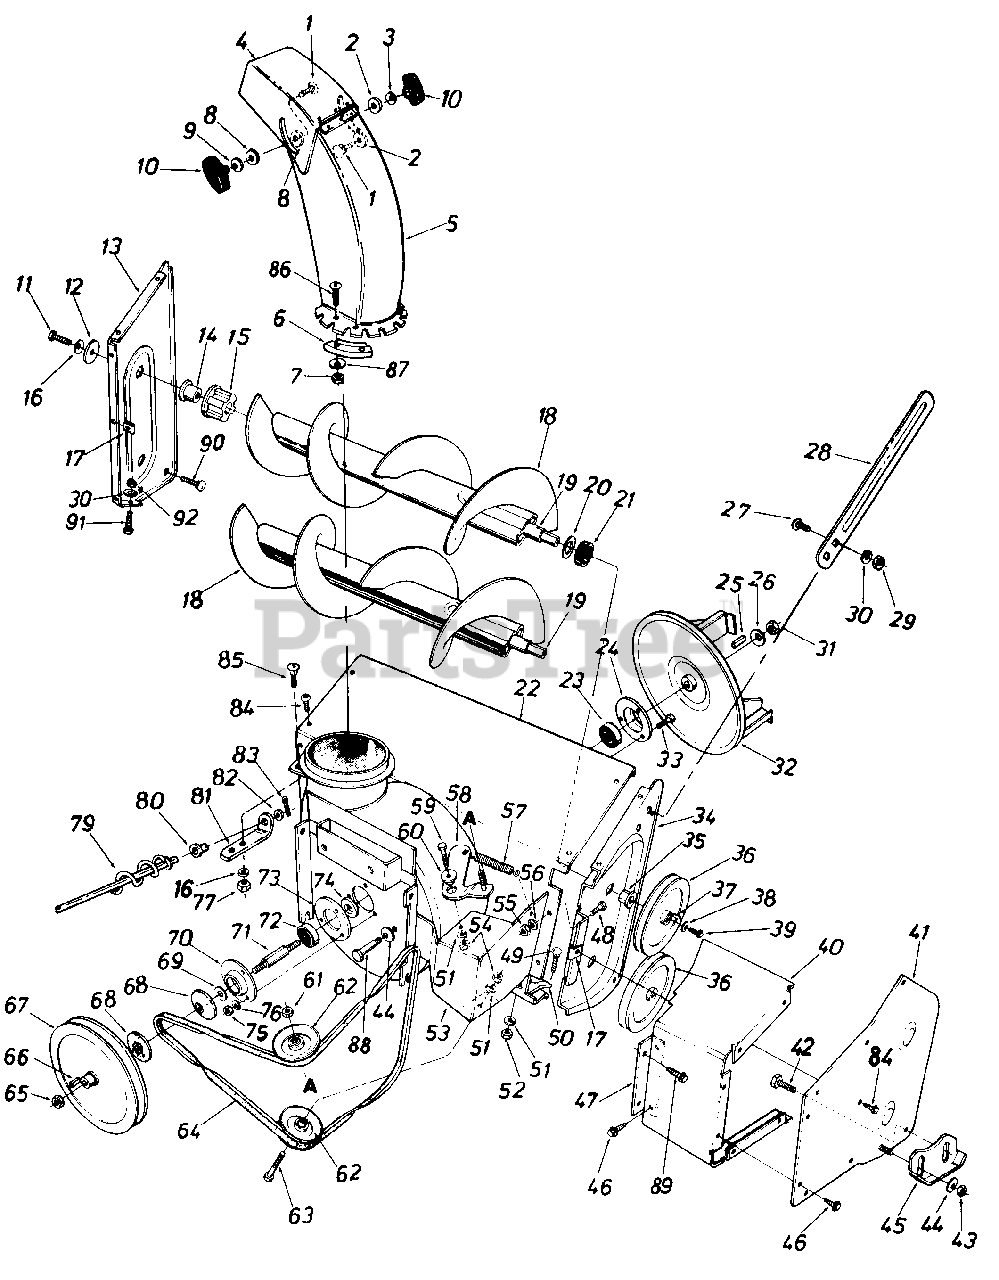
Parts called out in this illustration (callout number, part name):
1	Carriage Bolt 5/16-18 x 1.0" Lg.
2	Fl-Wash. .344" I.D. x 1.125" O.D.
3	Bell-Wash. .345" I.D. x .88" O.D.
4	Upper Chute
5	Lower Chute
6	Chute Flange Keeper
7	Hex Patch L-Nut 1/4-20 Thd.
8	Fl-Wash. .531" I.D. x 1.25" O.D.
9	Bell-Wash. .345" I.D. x .88" O.D.
10	Knob Handle Ass'y.
11	Hex Bolt 5/16-18 x 1.0" Lg. (Grade 5)
12	Fl-Wash. .32" I.D.
13	Spiral Housing Plate L.H.
14	Shaft Pin 1.0" O.D. x .94
15	Tubing Support Brg.
16	Bell-Wash. .345" I.D. x .88" O.D.
17	Speed Clip 1/4-20
18	Auger Ass'y. 22" x 6" Dia.
20	Fl-Wash. .760" I.D. x 1.75" O.D.
21	Spacer 1.25" I.D. x 1.50" O.D. x .58" Thk.
22	22" Spiral Housing Ass'y.
23	Ball-Brg. .787" I.D. x 1.85" O.D. x .551
24	Bearing Housing 1.85" I.D.
25	Sq. Key 3/16 x 1.50" Lg.
26	Bell-Wash. .630" I.D. x 1.25" O.D.
27	Carriage Bolt 5/16-18 x .62" Lg.
29	Hex Nut 5/16-18 Thd.
30	L-Wash. 5/16" I.D.
31	Hex Jam Nut 5/8-18 Thd.
32	11 " Dia. Blower Fan Ass'y.
33	Hex Bolt 5/16-18 x 1.00" Lg. (Grade 5)
34	Spiral Housing Plate R.H.
35	Hex Flange Brg. .751" I.D.
36	3/8" V-Pulley 5/8" I.D. x 5.5" O.D.
37	Sq. Key 3/16" X .75" Lg.
38	Bell-Wash. .265" I.D. x .75" O.D.
39	Hex Bolt 1/4-20 x .62" Lg.
40	Belt Cover Top
41	Belt Cover Side Ass'y.
42	Hex Bolt 3/8-16 x .75" Lg.
43	Hex Jam Nut 3/8-16 Thd.
44	Bell-Wash. .400" I.D. x .88" O.D.
47	Support Bracket
48	Hex Bolt 5/16-18 x .50" Lg.
49	Carriage Bolt 5/16-18 x .62" Lg.
50	Scraper Bar Kit 22"
51	Bell-Wash. .345" I.D. x .88" O.D.
52	Hex Nut 5/16-18 Thd.
54	Hex Nut 3/8-24 Thd.
55	Hex Nut 5/16-18 Thd.
56	L-Wash. 5/16" I.D.
57	Extension Spring .620" O.D. x 8" Lg
58	Idler Bracket Ass'y.
59	Hex Bolt 3/8-24 x .75" Lg.
60	Shld. Spacer .625" I.D.
61	Hex Ins. L-Nut 3/8-24 Thd.
62	"V"-Idler 2.62" O.D.
63	Hex Bolt 3/8-24 x 1.25" Lg.
64	V-Belt
65	Hex Cent. L-Nut 5/8-18 Thd.
66	Sq. Key 3/16 x .75" Lg.
67	5/8" "V"-Pulley .628" I.D. x 7.50" O.D.
68	3/8" "V"-Pulley Half .625" I.D. x 2.25" O.D.
69	Fl-Wash. .535" I.D. x 1.0" O.D.
70	Open Brg. Housing Ass'y.
71	Fan Spindle
72	Ball Brg. .787" I.D. x 1.85" O.D.
73	Spindle Reinforcement Plate
74	Spacer .790" I.D. x 1.0" O.D.
75	Hex Nut 5/16-18 Thd.
76	L-Wash. 5/16" I.D.
77	Hex Nut 5/16-18 Thd.
79	Chute Crank Ass'y. R.H. 39.0" Lg.
80	Plastic Bushing .380" I.D.
82	Fl-Wash. .385" I.D. x .62" O.D.
83	Cotter Pin 8/32" Dia. x .75" Lg.
84	Truss Mach. Scr. 1/4-20 x .50" Lg.
85	Carr. Bolt 5/16-18 x .75" Lg.
86	Truss Mach. Scr. 1/4-20 x .75"
87	Fl-Wash. .265" I.D. x .75" O.D. x .062
88	Shld. Bolt .5" Dia. x 2.11" Lg.
89	Hex Wash. Hd. Tap Scr. 5/16-24 x .5" Lg.
90	Carriage Bolt 3/8-16 x .62" Lg.
91	Hex Bolt 5/16-24 x .5" Lg.
92	Hex Nut 5/16-24 Thd.
